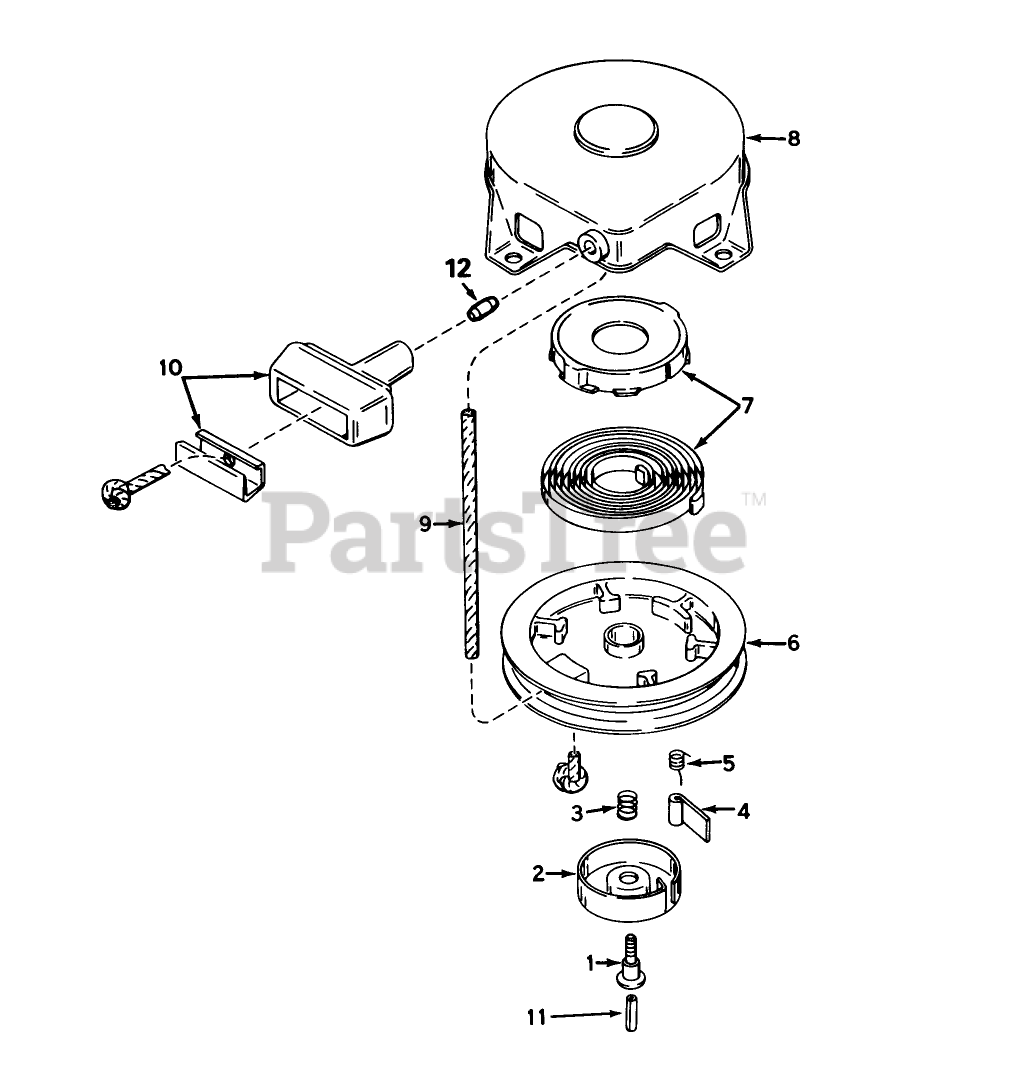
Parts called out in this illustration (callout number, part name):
1	Screw
2	Retainer
3	Spring-Brake
4	Dog-Starter
5	Spring-Dog
6	Pulley
7	Spring Keeper Assy
8	Housing Assy., Starter (Incl. Ref. #1)
9	Rope-Starter (98 cut to length)
10	Assy., Starter
11	Centering
12	Retainer-Starter Rope
